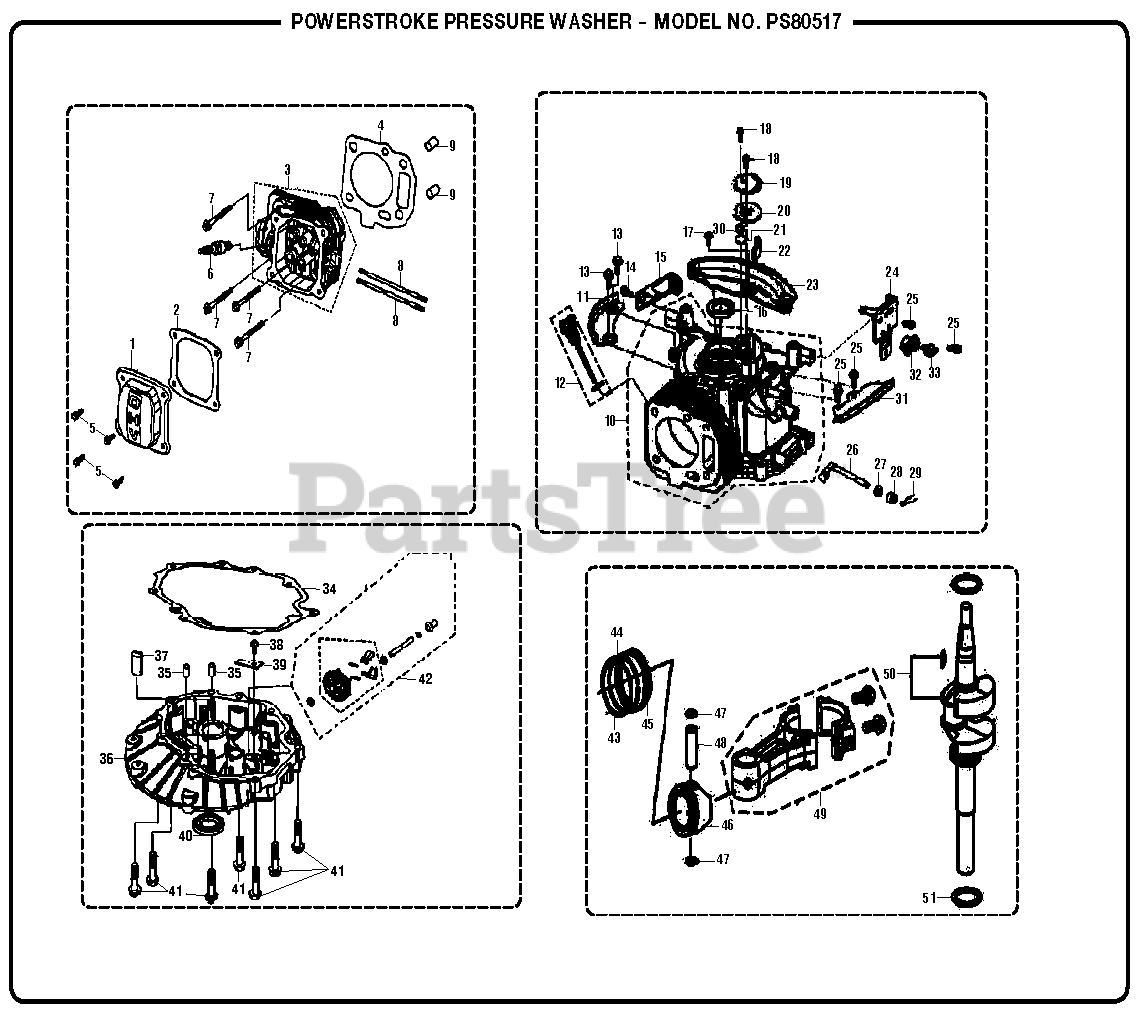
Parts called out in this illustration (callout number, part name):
1	Cylinder Head Cover
2	Cylinder Head Cover Gasket
3	Cylinder Head Assembly
4	Cylinder Head Gasket
6	Spark Plug
7	Cylinder Head Bolt
10	Crankcase Assembly
11	Crankcase Side Shield
12	Dipstick Assembly Oil
15	Fuel Tank Right Bracket
19	Breathe Groove Cover Plate
20	Breathe Groove Cover
21	Breathe Piece
22	Breathe Groove Strainer
23	Crankcase Rear Shield
24	Fuel Tank Left Bracket
26	Governor Arm
27	Washer
29	Pin
30	Breath Peice Return Spring
31	Crankcase Right Shield
32	Fuel Valve Holder
34	Crankcase Gasket
36	Crankcase Cover
37	Returning Oil Block
39	Governor Spindle Plate
42	Governor Gear Assembly
45	Oil Ring Set
47	Piston Pin Clip
49	Connecting Rod
50	Crankshaft Assembly
